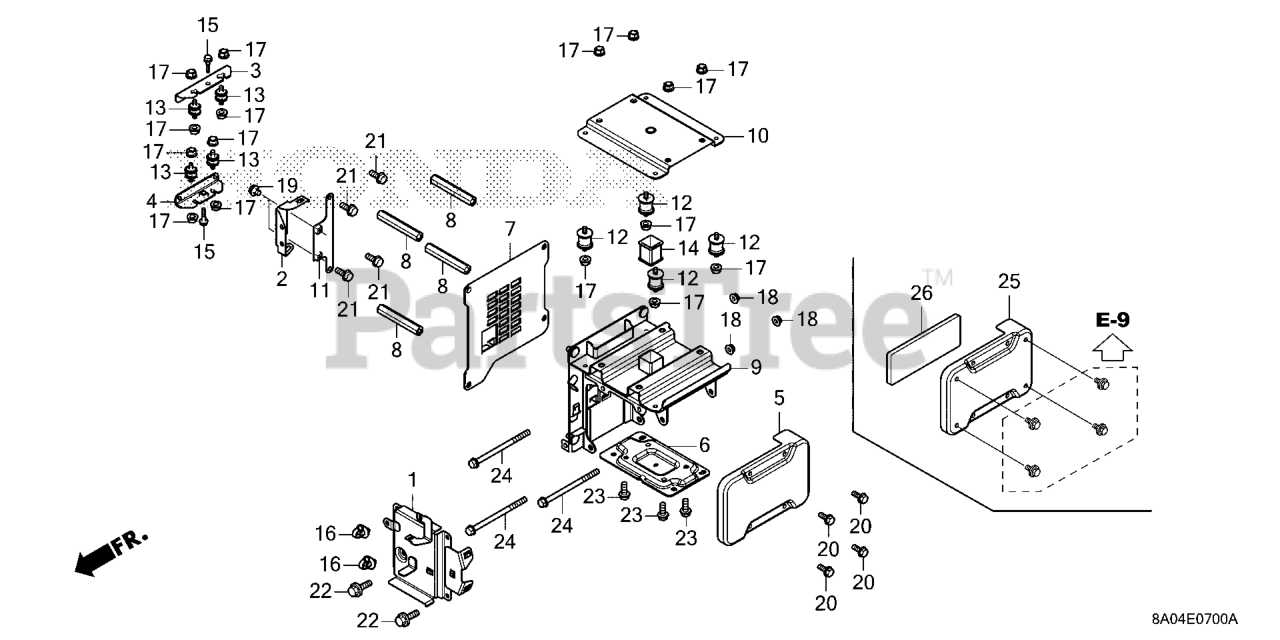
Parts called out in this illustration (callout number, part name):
1	BRACKET A, HARNESS
2	BRACKET B, HARNESS
3	STAY A, PDU
4	STAY B, PDU
6	BASE, MOTOR *NH105*
7	STAY C, PDU
8	COLLAR, SPECIAL
10	FRAME, BATTERY
11	STAY, BRACKET
12	RUB, BATTERY MOUNT
13	RUBBER, MOUNT
14	RUBBER A, STOPPER
15	BOLT, STOPPER (6X25)
16	CLIP, HARNESS BAND (145MM) (BLACK)
17	NUT, FLANGE (6MM)
18	NUT, FLANGE (8MM)
19	BOLT, FLANGE (6X10)
20	BOLT, FLANGE (6X16)
21	BOLT, FLANGE (6X16)
22	BOLT, FLANGE (6X20)
23	BOLT, FLANGE (8X20)
24	BOLT, FLANGE (8X125)
25	FRAME, SIDE *NH1*
26	SHEET, SILENT
